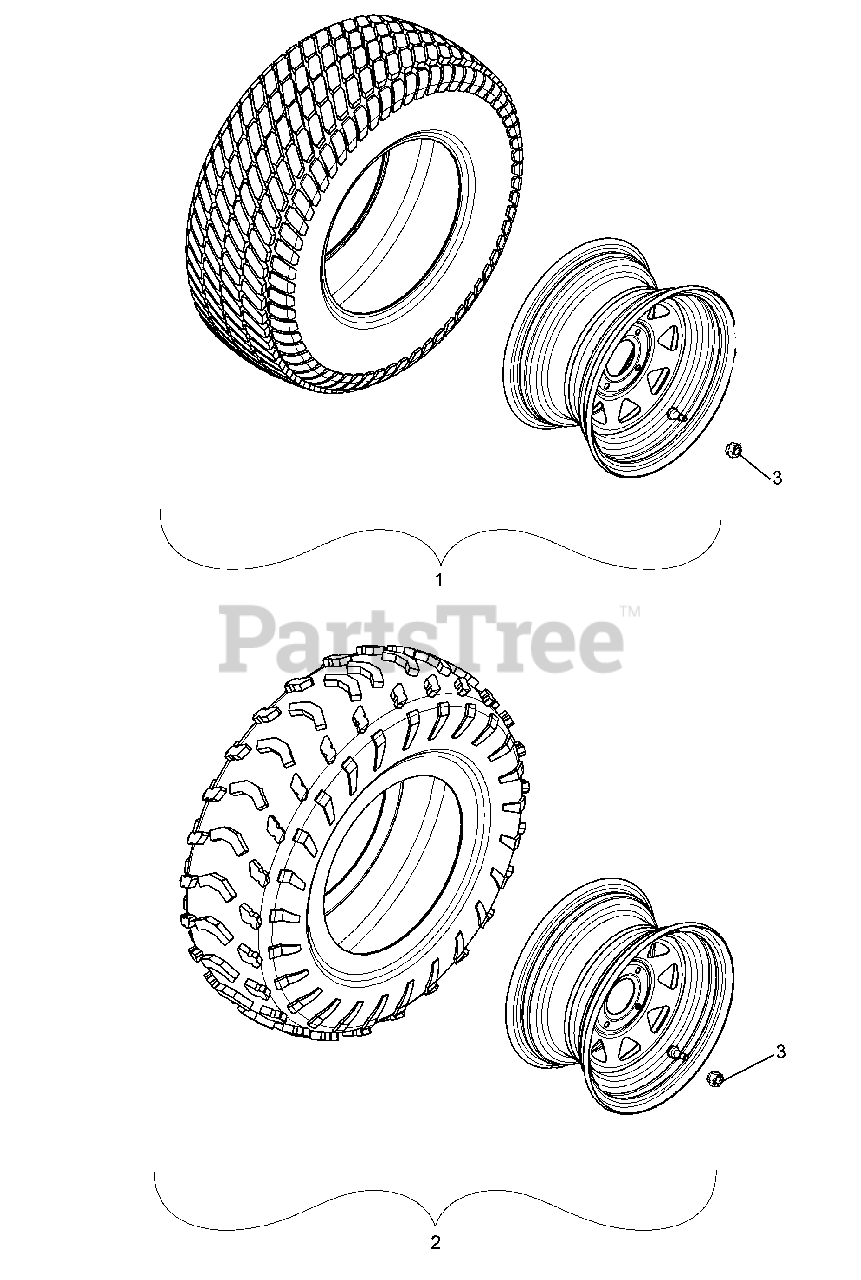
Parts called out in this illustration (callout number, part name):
1	TIRE/WHEEL ASSEMBLY TREKER TURF FRONT (996125)
2	AT TIRE/RIM, BLACK RIGHT FRONT (996123, 146, 147)
2	AT TIRE/RIM, BLACK LEFT FRONT (996123, 146, 147)
3	WHEEL NUT .500-20 YZ
